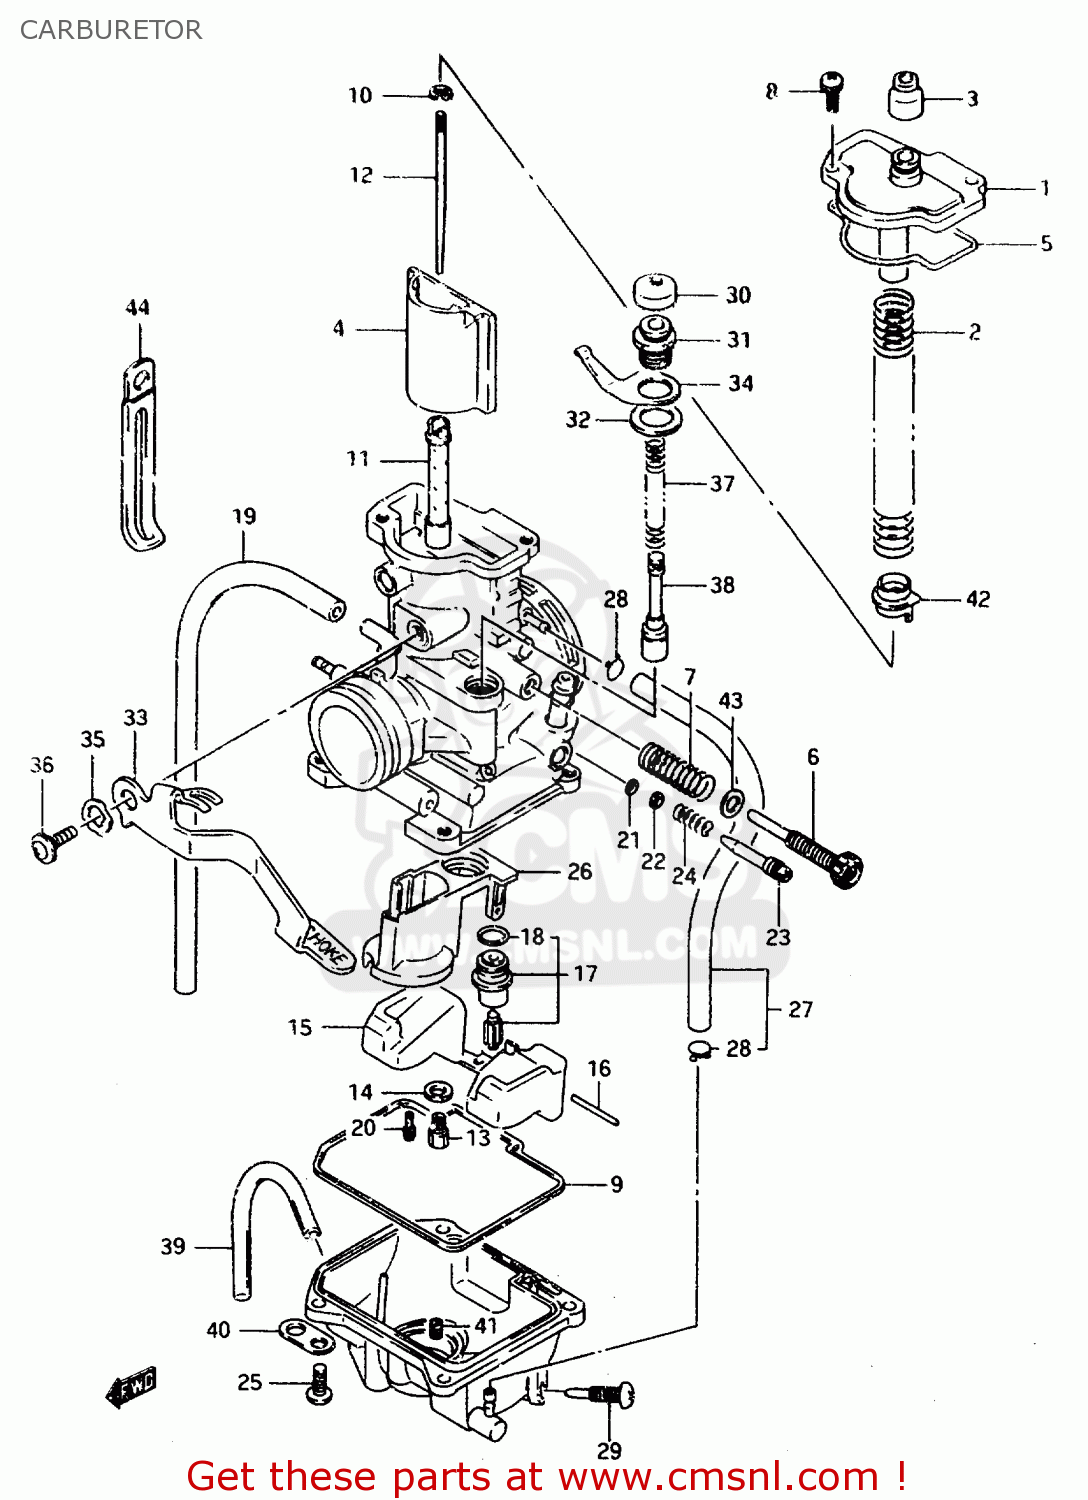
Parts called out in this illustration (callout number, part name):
1	CAP,TOP
2	SPRING
3	CAP
4	VALVE,PISTON(CA:4.0)
5	O RING,TOP CAP
6	ADJUSTER
7	SPRING
8	SCREW
9	SEAL,CARBURETOR
10	CLIP
11	JET,NEEDLE(N-9)
12	NEEDLE,JET
13	JET,MAIN(150)
14	WASHER,NEEDLE NOZZLE
15	FLOAT
16	PIN,FLOAT
17	VALVE ASSY,NEEDLE
18	O RING
19	HOSE
20	JET,PILOT
21	O RING,PILOT AIR SCREW
22	WASHER
23	SCREW,AIR
24	SPRING
25	SCREW
26	HOLDER
27	HOSE ASSY
28	CLIP
29	SCREW,DRAIN
30	CAP,PLUNGER
31	HOLDER,GUIDE
32	WASHER
33	LEVER, STARTER
34	PLATE,SPRING
35	WASHER
36	SCREW
37	SPRING
38	PLUNGER,STARTER
39	HOSE
40	PLATE,CARBURETOR
41	JET,POWER,85
42	RING
43	WASHER
44	CLAMP
